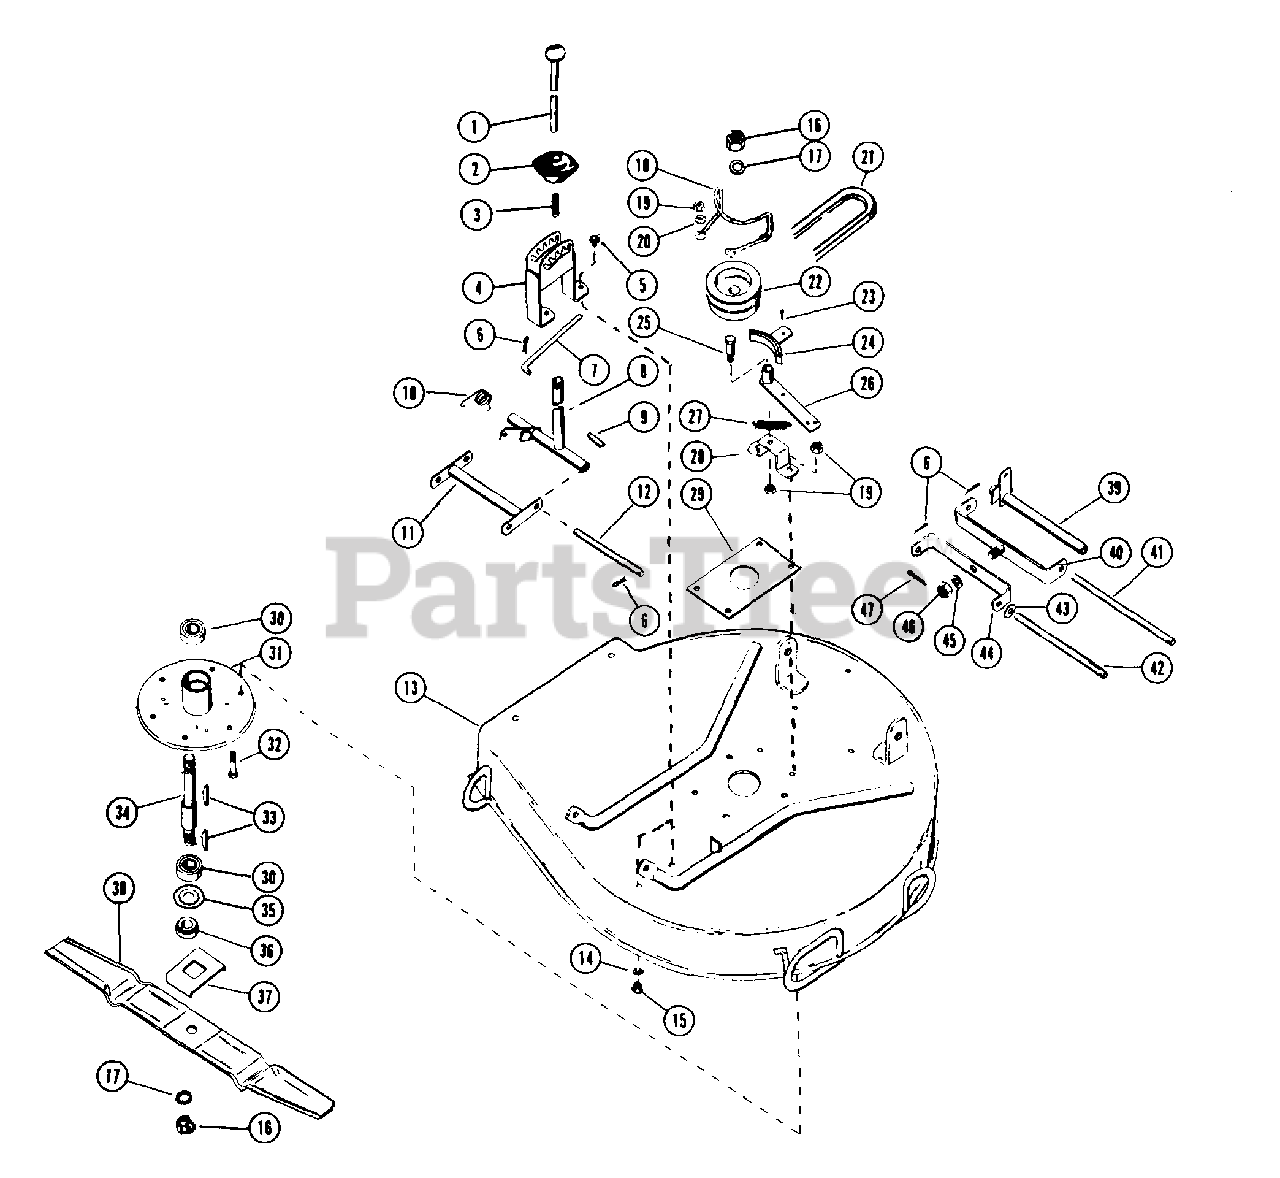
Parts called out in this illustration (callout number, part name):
1	HGHT CNTL PLNGR
2	SHIFT BALL
3	SG-COMP ??X.44X?? WLD 10
4	MWR HGHT QUAD
5	BLT-HEX .31-18X.75 PL GR2
6	PIN-COTR .12X1.0 PL
7	HGHT LINK ROD
8	HGHT CNTL ARM
9	PIN-ROLL .250X1.25
10	SG-TORS .162X.75X.648
11	FLOATING LINK
12	ADAPTER PIN
13	MOWER PAN
14	WSHR-LK .312X.097 PL HVY
15	NUT-HEX .312-18
16	NUT-JAM .75-10 PL
17	WSHR-LK .750X.188 MED PL
18	MOWER BELT FINGER
19	NUT-LK-CTR .375-16 GR A PL
20	THROTTLE CONTROL
21	V-BELT, 5L-RAW EDGE
22	MOWER SHEAVE
23	RVT .25X.50 RH ST
24	BLADE BRAKE
25	SHOULDER BOLT .50 X 1.75
26	BLADE BRAKE ARM
27	SG-TENS .072X.51X5.31 WLD 25
28	BLADE BRAKE SUPPORT
30	BRG-BALL .751X1.78X.61
31	SPINDLE HOUSING
32	BLT-HEX .38-16X1.00 PL
33	KEY-WDRF .188X.75X.313 SAE 9
34	MOWER SPINDLE
35	BEARING SLINGER
36	RETAINER HUB
37	BLADE TRAY
38	BLADE, MOWER
39	REAR RAISING BRACKET
41	REAR BRACKET PIN
42	HANGER PIN
43	WSHR-FL-STL .531X1.062X.095 PL
45	WSHR-FL-STL .630X1.005X.062 PL
46	NUT-JAM-SL .625-18
47	PIN-COTR .12 X 1.25 PL
